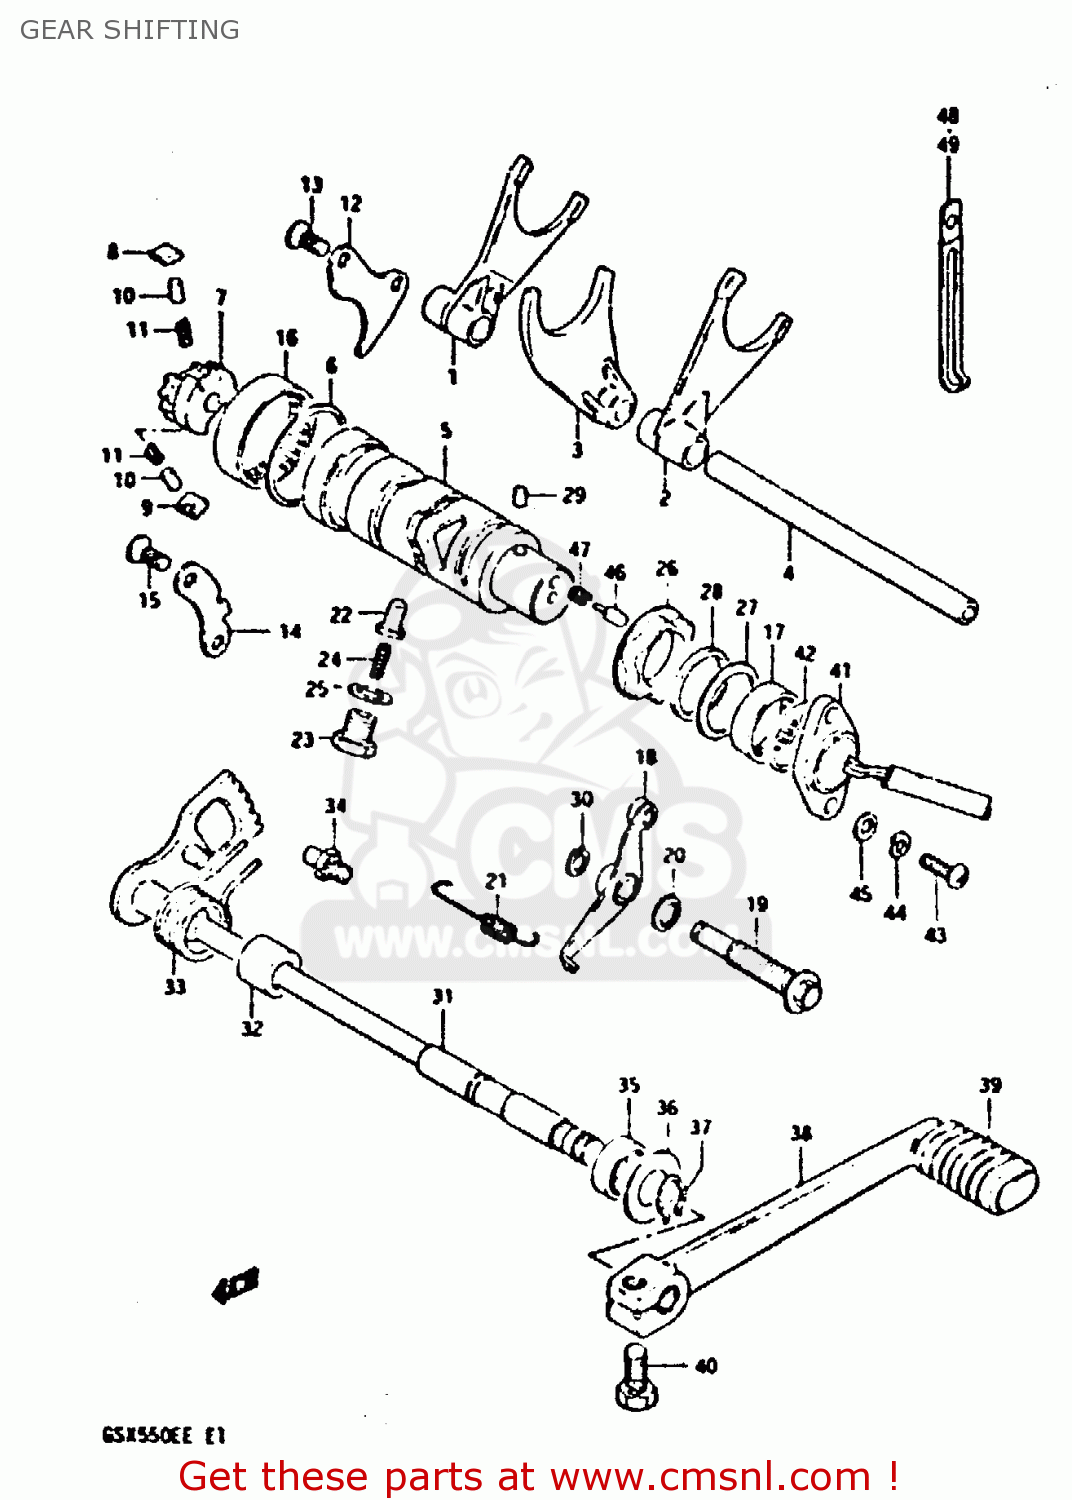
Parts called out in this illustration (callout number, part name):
1	FORK,GEAR SHIFT NO.1
2	FORK,GEAR SHIFT NO.2
3	FORK,GEAR SHIFT NO.3
4	SHAFT,GEAR SHIFT FORK
5	CAM,GEAR SHIFT
6	WASHER (40X49X1)
7	SHIFTER,GEAR SHIFT CAM
8	PAWL,GEAR SHIFT NO.1
9	PAWL,GEAR SHIFT NO.2
10	PIN(5X8)
11	SPRING
12	LIFTER,GEAR SHIFT PAWL
13	SCREW
14	GUIDE,GEAR SHIFT CAM
15	SCREW
16	BEARING(43X49X12)
17	BEARING(25X32X12)
18	STOPPER,GEAR SHIFTING
19	HOLDER,SHIFTING CAM STOPPER
20	GASKET(10X14X3.6) (NAS)
21	SPRING
22	STOPPER,GEAR SHIFTING
23	HOLDER,GEAR SHIFT CAM STOP SPR
24	SPRING
25	GASKET(14X19.2X2) (NAS)
26	PLATE,GEAR SHIFT CAM STOPPER
27	WASHER
28	WASHER
29	PIN 4X6
30	CIRCLIP
31	SHAFT,GEAR SHIFT
32	SPACER(12X20X15.3)
33	SPRING
34	STOPPER,GEAR SHIFT CAM
35	OIL SEAL
36	WASHER (12.5X27X1.6)
37	SPRING,RETAINER
38	LEVER ASSEMBLY,GEAR SHIFTING
39	RUBBER,PEDAL
40	BOLT
41	TERMINAL BASE ASSY,GEAR SHIFT
42	O-RING (D:2.4 ID:26.2)
43	SCREW(5X14)
44	LOCK WASHER
45	WASHER
46	PIN(5X15.5)
47	SPRING
48	CLAMP L:35
49	CLAMP
